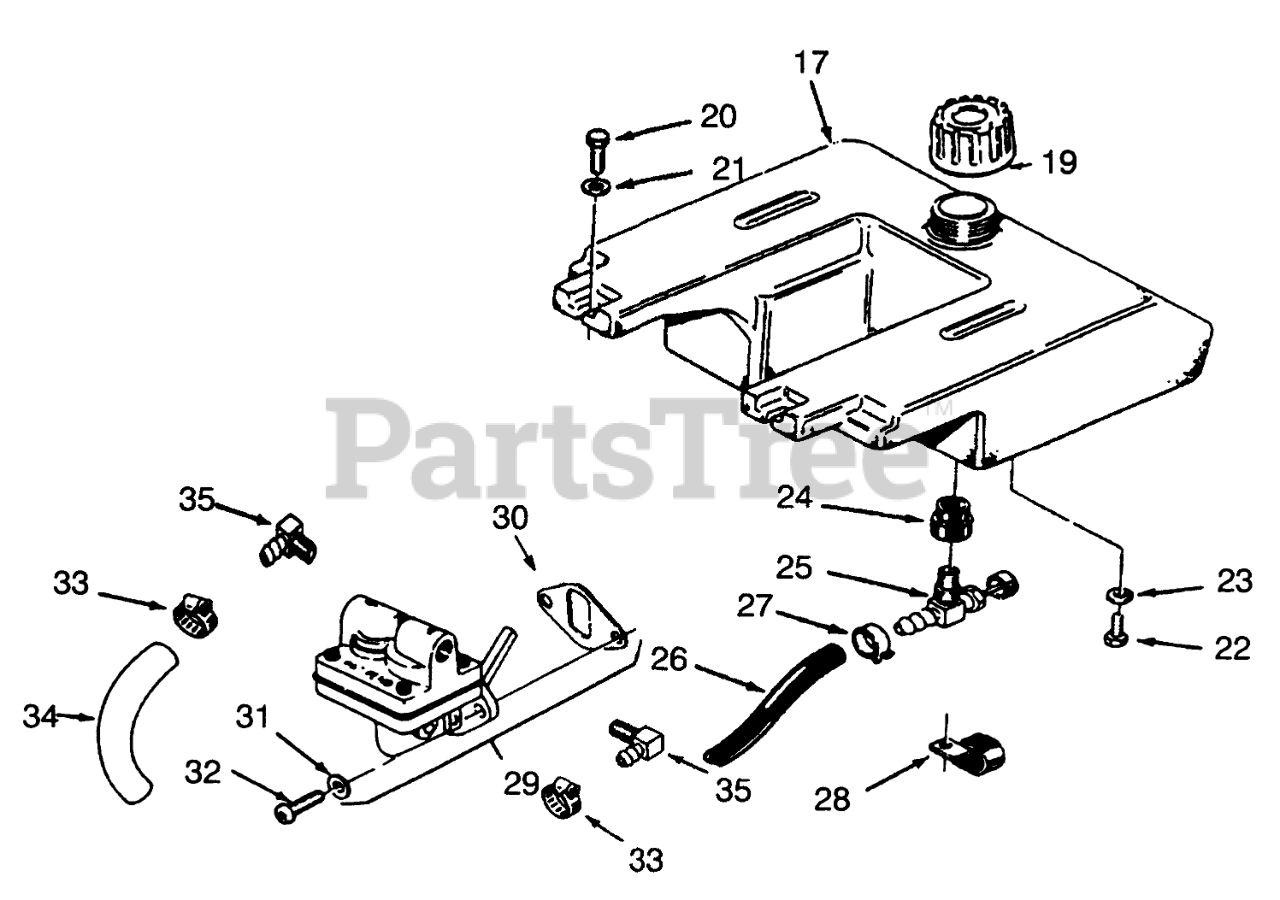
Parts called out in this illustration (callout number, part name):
17	TANK-FUEL
18	GAS CAP ASM
20	Bolt
21	WASHER-FLAT
22	SCREW-HH
23	WASHER-LOCK
24	BUSHING
25	VALVE-FUEL
26	Fuel Line 62
27	Clamp
28	Clamp
29	Pump Assy-Fuel (Incl. Ref.#30 & 31)
30	Gasket-Fuel Pump
31	Washer
32	Screw-Pozidrive
33	Clamp
34	Line-Fuel 5" Lg
35	Connector 90
